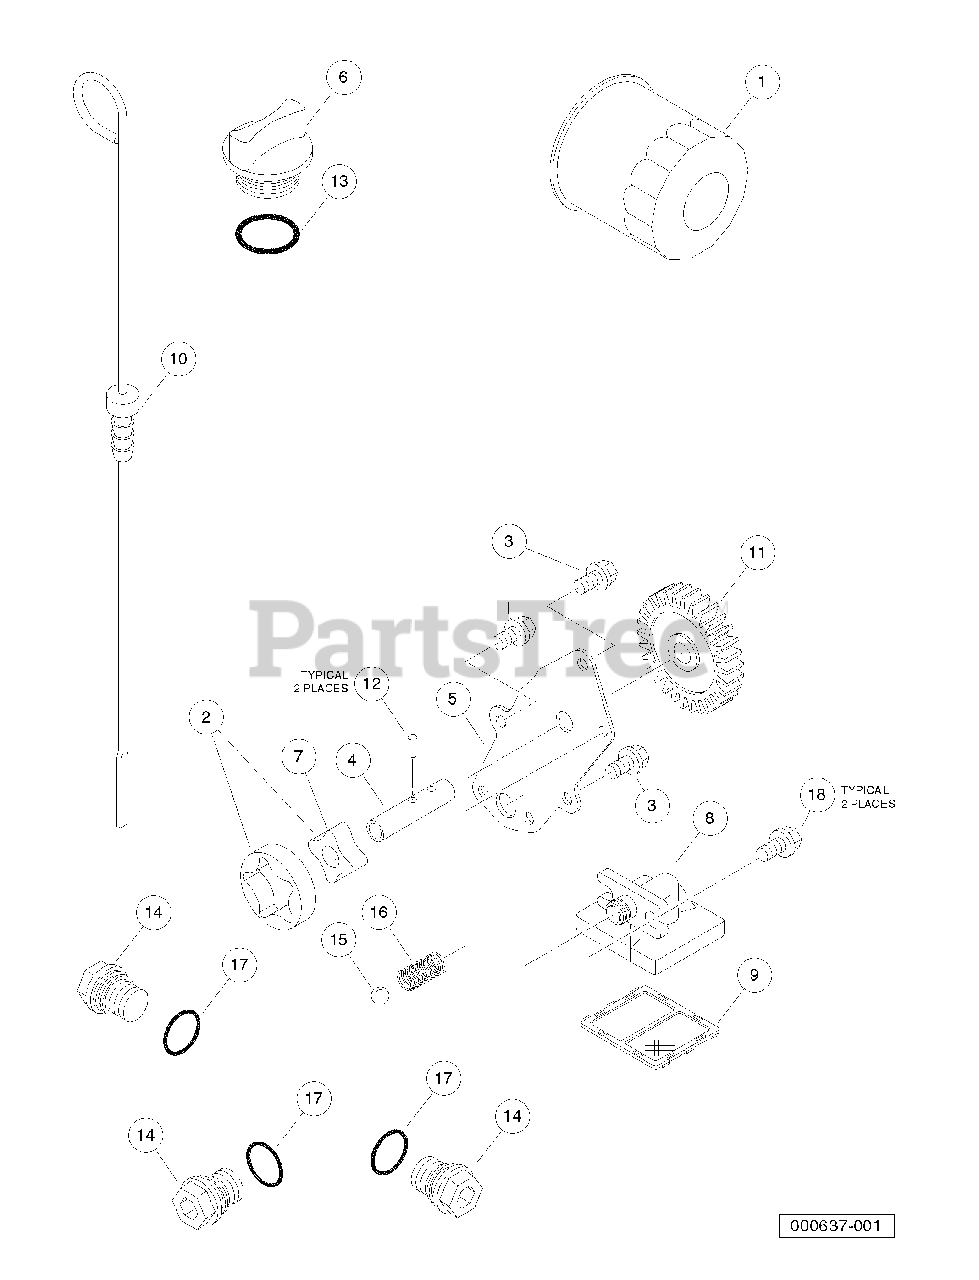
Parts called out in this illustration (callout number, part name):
1	Filter, Oil
2	Oil Pump And Rotor
3	Bolt, Flg, M6 X 1.0 X 12
4	Shaft, Oil Pump, Fh
5	Plate, Oil Pump, Fh
6	Cap, Oil, Fill, Fh
7	Rotor, Pump, Oil, In, Fh
8	Pickup, Oil, Fh
9	Screen, Pickup, Oil, Fh
10	Gauge, Oil, Fh
11	Gear, Spur, Oil Pump, Fh
12	Pin, Oil Pump, Fh
13	O-ring, Cap, Oil, Fill, Fh
14	Plug, Oil Drain, Fh
15	Ball, Oil Pump, Fh
16	Spring, Oil Pump, Fh
17	O-ring, Drain Plug, Oil, Fh
18	Bolt, Oil Pickup, Fh
